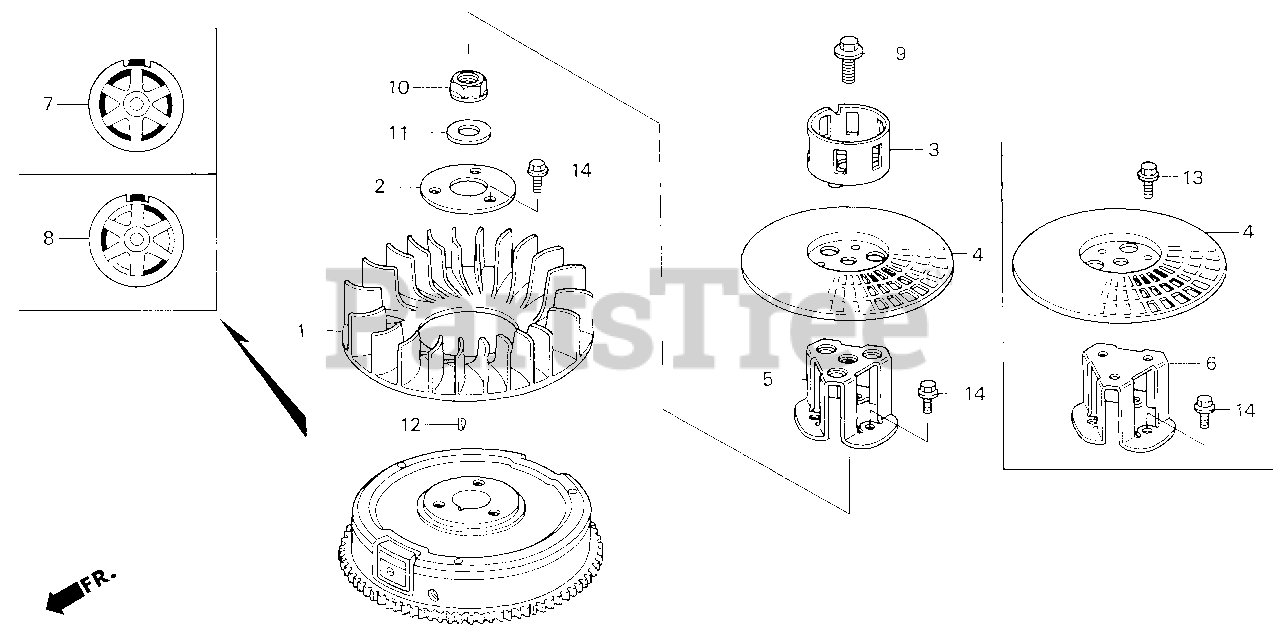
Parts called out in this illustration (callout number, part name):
1	FAN, COOLING
4	GRID, SCREEN
6	HOLDER, SCREEN GRID
7	FLYWHEEL
10	NUT, FLANGE (20MM)
11	WASHER (20MM)
12	KEY, SPECIAL WOODRUFF (25X18)
13	BOLT, FLANGE (6X12)
14	BOLT, FLANGE (8X16)
